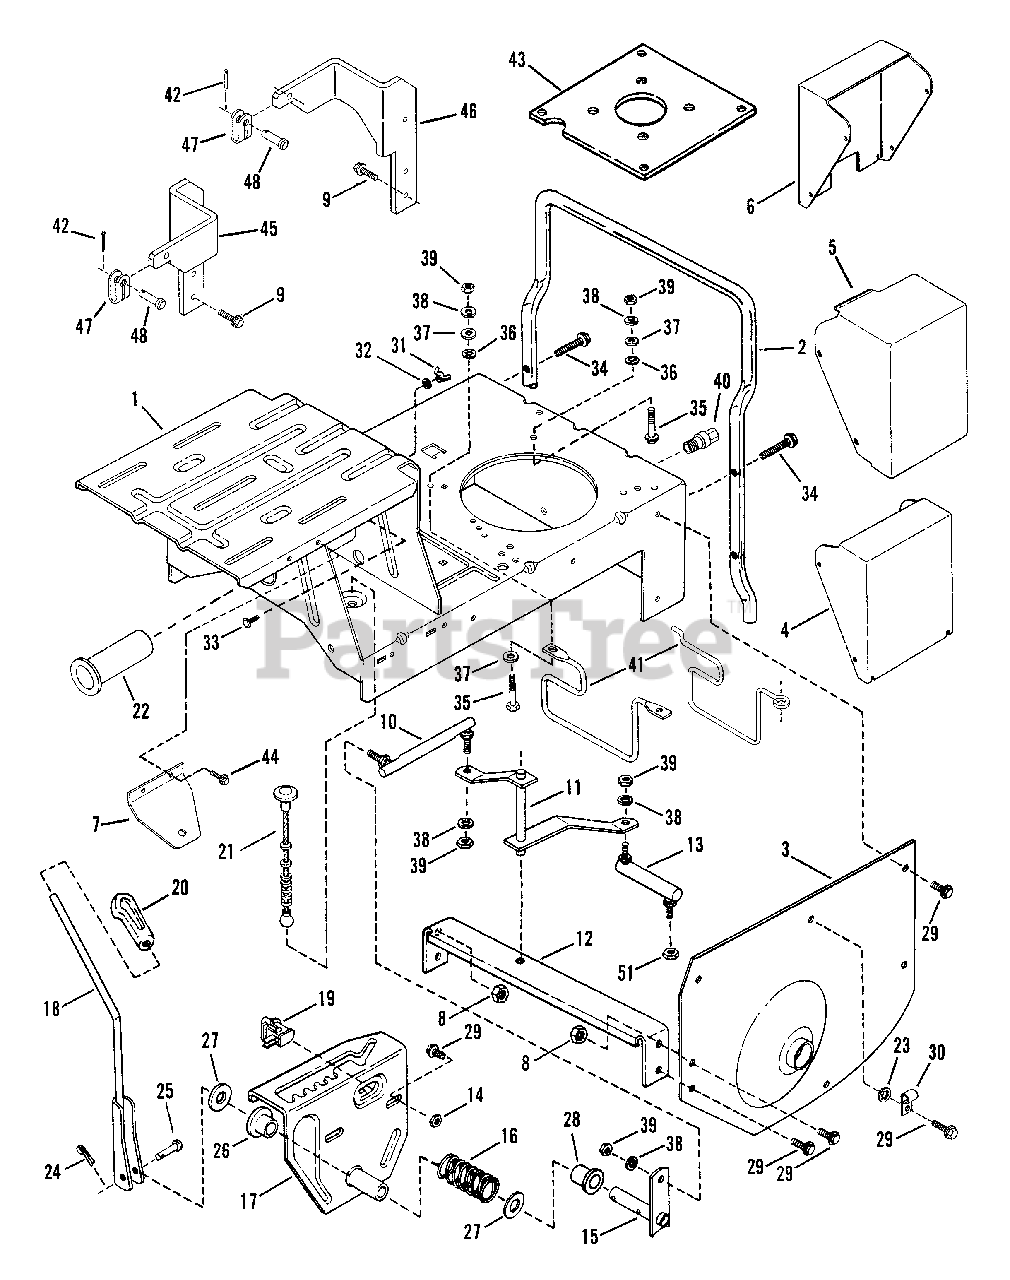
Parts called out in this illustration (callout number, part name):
1	CASE, Main
2	BUMPER, Rear
3	FENDER, Left Hand
4	COVER
5	COVER, Battery
6	COVER, Switch
7	PLATE, Choke
8	NUT, 5/16-18 Hex Flange Lock
9	SCREW, 5/16-18 1" Self-Tapping
10	LINK, Shift (Long)
11	ARM, Shift
12	BRACE, Cross
13	LINK, Shift (Short)
14	NUT, 5/16-18 Hex
15	ARM, Shift Handle
16	SPRING, Shift Handle
17	DETENT, Shift
18	HANDLE, Shift
19	SWITCH, Seat
20	KNOB, Shift Handle
21	CABLE, Deck Support 5.0", 7 Furrels (Used on 25" thru 33" models)
22	BUSHING, Pilot
23	WASHER, 5/16 Internal Tooth Lock
24	PIN, 3/32 x 3/4" Cotter
25	PIN, 1/4 x 1-3/4" Tapered Clevis
26	BUSHING, Nylon
27	WASHER, Thrust
28	BUSHING, Nylon
29	SCREW, 5/16-18 x 5/8" Self-Tapping
30	CLIP, Wire
31	NUT, #10-24 Locking Wing
32	RETAINER, #10 Bolt
33	BOLT, #10-24 x 1/2" Carriage
34	SCREW, 5/16-18 x 1-1/2" Self-Tapping
35	SCREW, 5/16-24 x 1-3/4" Hex Head Cap
36	RETAINER, 5/16 Bolt
37	WASHER, 5/16" Flat
38	WASHER, 5/16" Split Lock
39	NUT, 5/16-24 Hex
40	DRAIN, Oil (Short)
41	GUIDE, Belt
42	PIN, 3/32 x 3/4" Cotter
43	PLATE, Engine
44	SCREW, 1/4-20 x 5/8" Self-Tapping
45	DECK WING, Rear 42" Models (Left)
46	DECK WING, Rear 42" Models (Right)
47	BRACKET, Cable
48	PIN, 3/8 x 1 1/16" Clevis
51	NUT, 5/16-24 Hex Flange Lock
